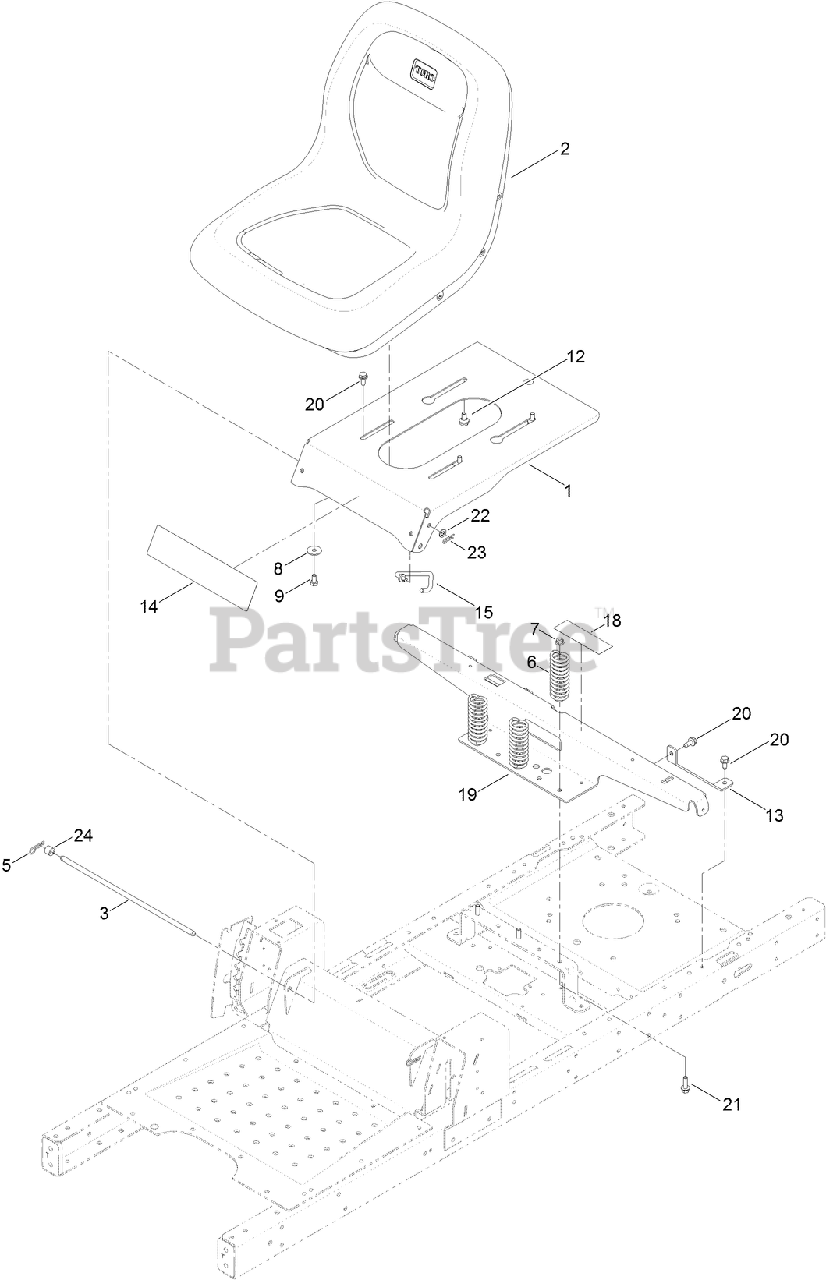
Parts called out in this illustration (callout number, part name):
2	SEAT-18 INCH
3	ROD-STOP
5	PIN-COTTER
6	SPRING-COMPRESSION
7	NUT-HF, NI
8	WASHER-PIVOT
9	SCREW-HH
12	BOLT-SHOULDER,HFH
13	SUPPORT-TANK, REAR
14	DECAL-TIMECUTTER
15	STOP-SEAT
18	DECAL-SERVICE, CE
19	SUPPORT-POD, WIDE
20	SCREW-HWHTF
21	SCREW-HHF
22	WASHER-PLAIN
24	BUSHING-LEVER, LIFT
